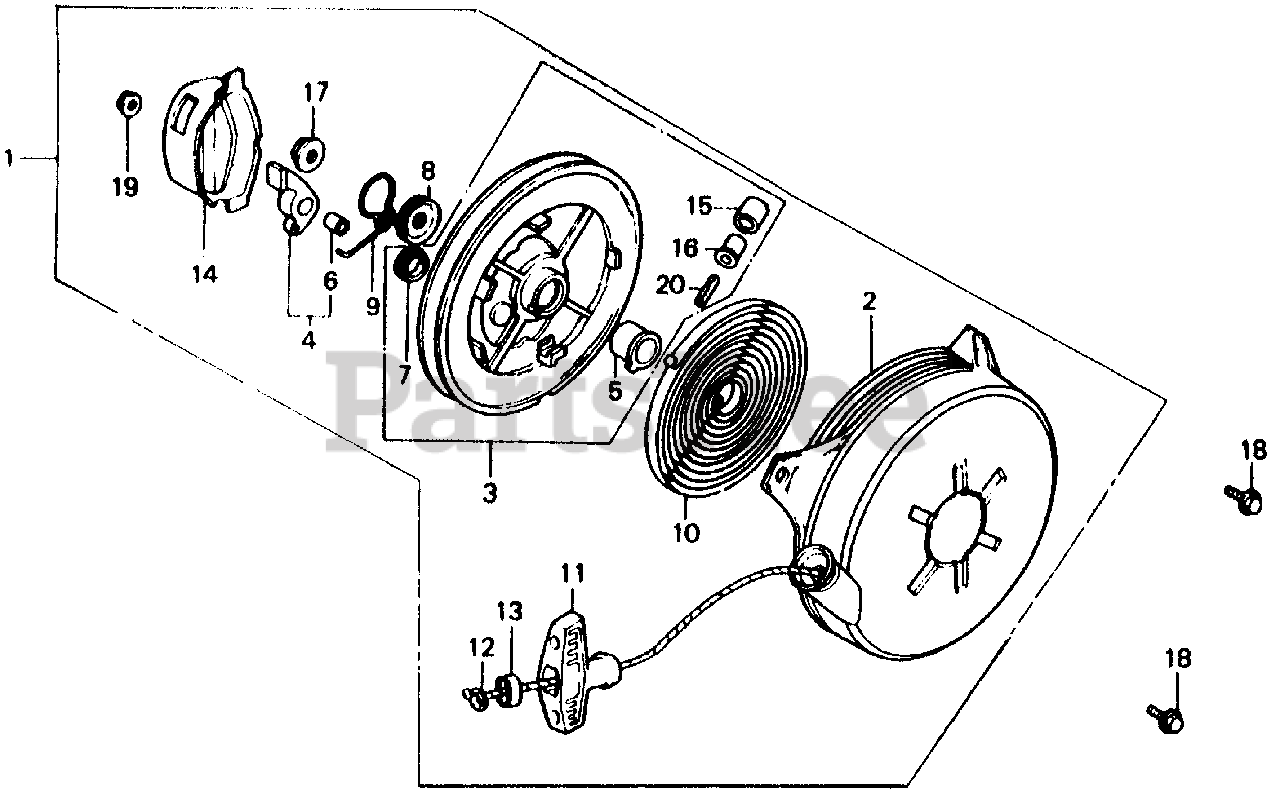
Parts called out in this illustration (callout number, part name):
1	STARTER ASSY., RECOIL *R8* (BRIGHT RED)
2	CASE, STARTER *R8* (BRIGHT RED)
3	REEL, STARTER
5	BOSS, REEL
6	BUSH, RATCHET
7	BUSH, REEL STARTER
8	PLATE, FRICTION
9	SPRING, FRICTION
10	SPRING, RETURN
11	GRIP, STARTER
12	ROPE, RECOIL STARTER (#5X55")
13	SUPPORT, GRIP
14	COVER, REEL STARTER
15	ROLLER, GUIDE
16	BUSH, ROLLER
17	NUT, SELF-LOCK (8MM)
18	BOLT-WASHER (6X10)
19	NUT, FLANGE (5MM)
20	PIN, SPRING (3X18)
